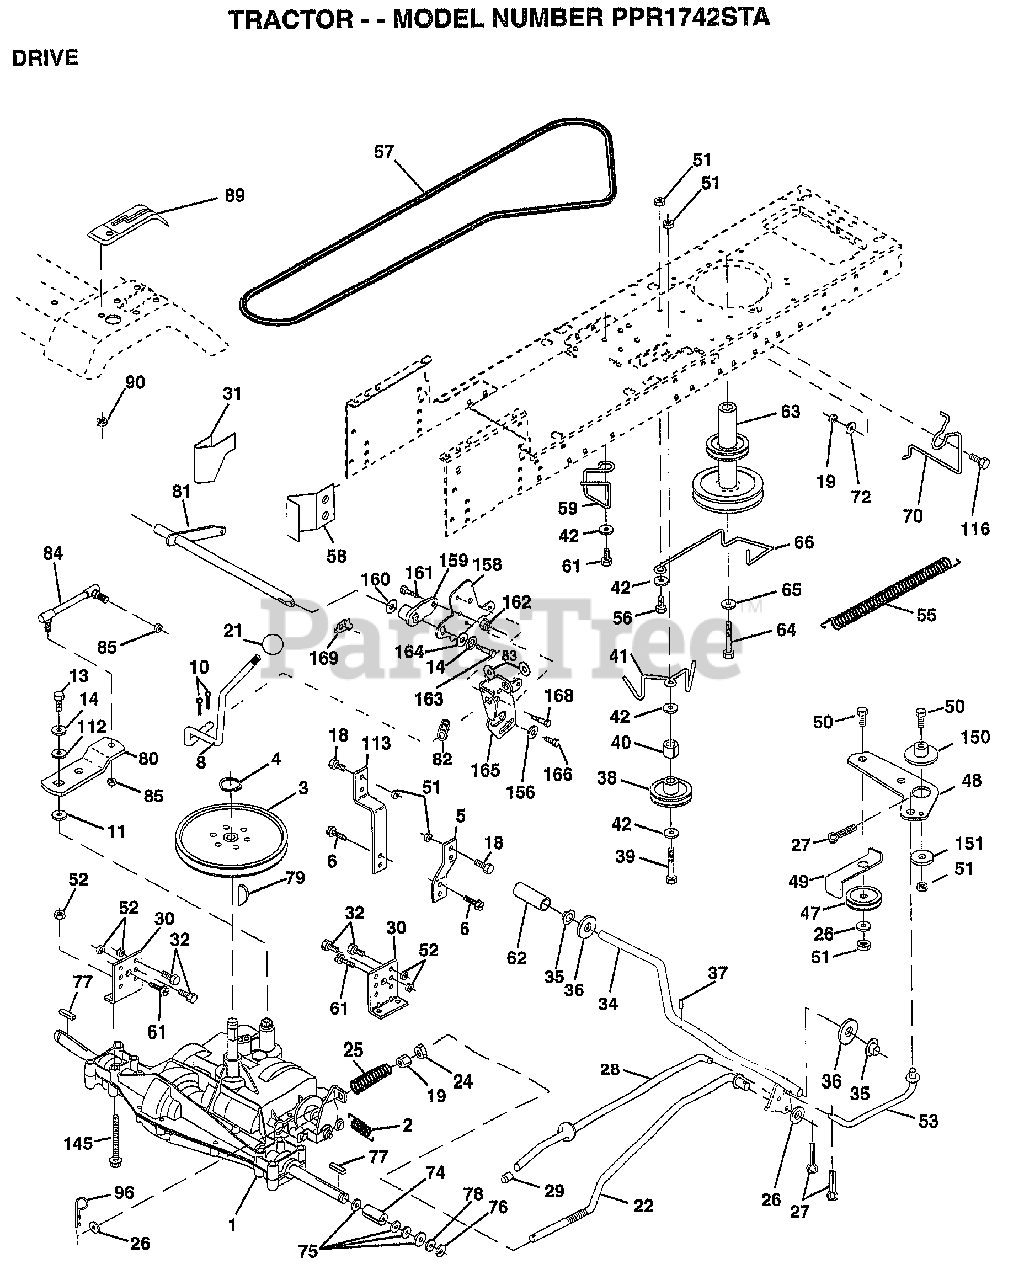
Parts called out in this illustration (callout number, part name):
2	SPRING.BRAKE.RETU
3	PULLEY TRANS
5	STRAP TORQUE
6	SCREW
8	ROD.SHIFT.FENDER.ADJ.LT.CRD
10	PIN COTTER 1/8
11	WASH-SHFT PLT LT
13	BOLT.1/4-28.W/PAT
14	LOCKWASHER
18	BOLT
19	NUT
21	KNOB DLX BLK/BLK
22	BRAKE ROD
24	NUT
25	SPRING ROD LT
26	WASHER
27	COTTER PIN
28	ROD.BRAKE.PARK.LT
29	PLUNGER CAP T
30	TRANSAXLE MTG BKT
31	"KEEPER,BELT LH T"
32	BOLT
34	SHAFT ASM-PEDAL F
35	NYLON BEARING
36	WASHER LT
38	FLAT IDLER PULLEY
39	BOLT
40	SPACER T
41	"KEEPER,BELT.IDLER FLAT"
42	WASHER
48	BELLCRANK.CLUTCH
49	RETAIN BELT
53	"LINK, CLUTCH T"
55	"SPRING, RETURN LT"
58	"KEEPER,BELT RH T"
59	KEEPER BELT CNTSP
61	SCREW
62	PEDAL COVER T
63	PULLEY.ENGINE
64	BOLT
65	LOCKWASHER
66	KEEPER-BELT
70	KEEPER BELT ENG
72	WASHER
74	SPACER AXLE
75	WASHER
76	E-RING LT
77	SQUARE KEY
78	WASHER
80	"ARM.SHIFT.20""TIRE"
81	SHAFT.ASM.CROSS
82	"SPRING,TORSION"
83	WASHER
84	LINK.TRANSAXLE.PMST/DANA
85	NUT.CNT.LOCK.1/4
89	CONSOLE.SHIFT.SLT
90	NUT
96	RETAINER M
112	WASHER LT
113	"STRAP,TORQUE"
116	BOLT RDHD 3/8-16
145	BOLT.HEX.FLGHD
150	BUSHING.BELLCRANK.GRD.DR
151	WASHER
156	WASHER.SRRTD.5/16
158	BRKT.SHIFT.MOUNT
159	HUB.SHIFT
160	WASHER
161	BOLT T
164	WASHER.5/8X.281X10GA
165	BRKT.PIVOT.LEVER
166	SCREW.5/16-18X5/8
168	BOLT.SHOULDER.5/16-18X.561
169	PLATE.FASTENING
